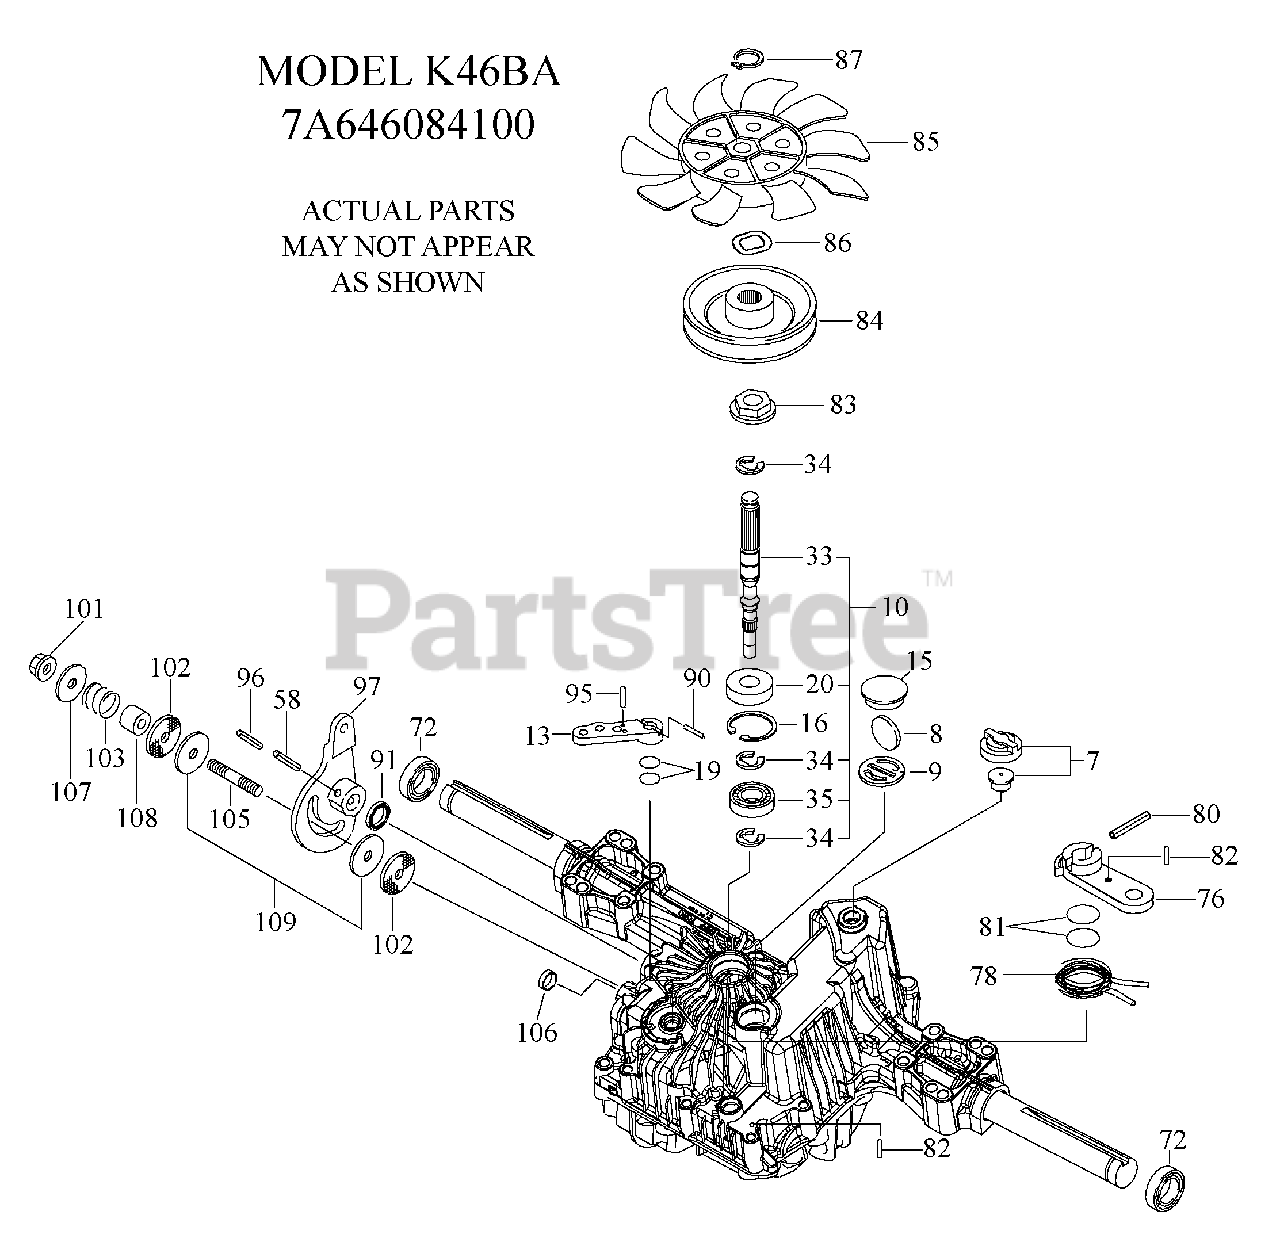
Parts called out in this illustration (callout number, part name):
7	Vent Valve 15
8	Magnet
9	Magnet Holder
10	Pump Shaft/Bearing Kit
13	Bypass Lever
15	Sealing Cap 30
16	Snap Ring C 35
19	O-Ring 1a P10a
20	Seal Tc 153507
33	Pump Shaft (Standard)
35	Bearing 6202c3
58	Roll Pin 6 x 40
72	Seal 19 x 32 x 8
76	Brake Lever
78	Brake Return Spring
80	Spring Pin 5 x 32
81	O-Ring 1a P12
82	Spring Pin 4x16
83	Spine Collar
84	Pulley L
85	Fan, Black
86	Wave Washer
87	Snap Ring
90	Spring Pin 3.0a x 20
91	Oil Seal 16 x 22 x 03
95	Spring Pin 3.0a x 16
96	Roll Pin 3.5 x 40
97	Control Lever
101	Lock Nut 10
102	Washer 10 x 40 x 4
105	Stud 10 x 60
106	Sealing Cap 18
107	Washer 10 x 36 x 2.8
108	Collar 10 x 20 x 17
109	Friction Plate Kit
